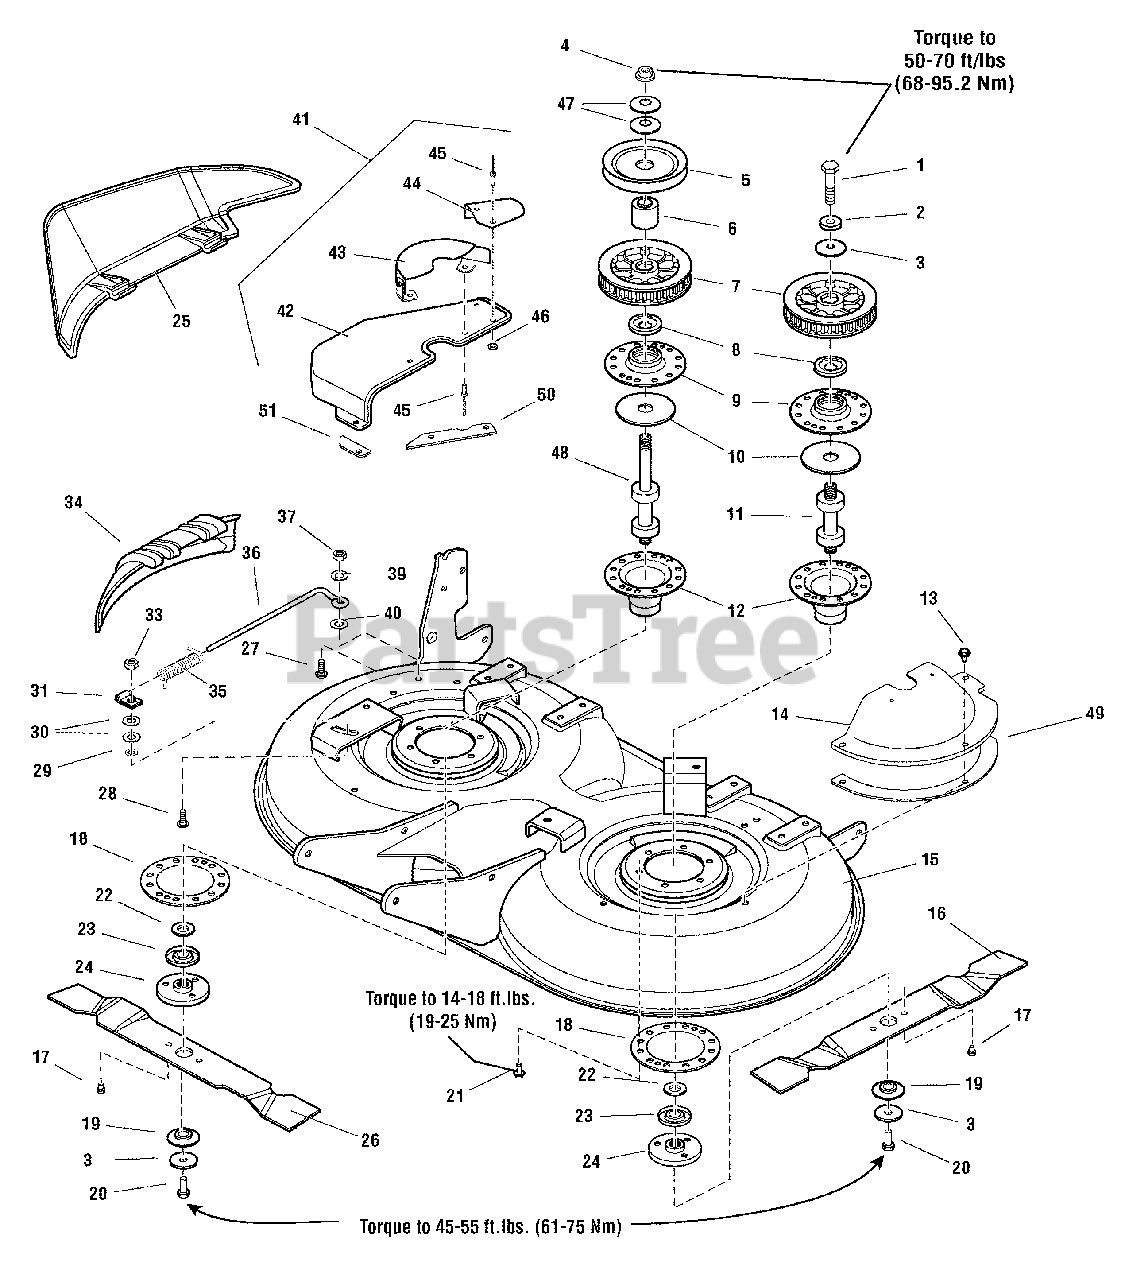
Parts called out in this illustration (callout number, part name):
1	CAPSCREW, Hex Head, 7/16-14 x 2-3/4 G8
2	WASHER, 7/16
3	WASHER, Spring
4	NUT, Hex Flange, 9/16-18
5	PULLEY, Drive 5"
5	PULLEY, Drive 6"
6	HUB
7	SPROCKET & FLANGE ASSEMBLY, w/Screws, 38 Tooth
8	SHIELD, Bearing Upper, Arbor
9	HOUSING, Arbor Top
10	GASKET, Foam Poly
11	ARBOR SHAFT & BEARINGS ASSEMBLY
12	HOUSING, Arbor Bottom with Lube Fitting
13	CAPSCREW, Taptite Hex Washer Head, 5/16-18 x 3/4
14	COVER, Arbor, LH
15	HOUSING ASSEMBLY, 40", Red
16	BLADE, Mower, LH
17	PIN, Blade
18	ADAPTOR, Arbor
19	WASHER, Spline
20	CAPSCREW, Hex Head, 7/16-14 x 2-1/4 G8
21	CAPSCREW, Taptite Hex Washer Head, 5/16-18 x 1
22	WASHER, Shim
23	SHIELD, Arbor Bearing, Lower
24	ADAPTER, Blade
25	DEFLECTOR, Discharge
26	BLADE, Mower, RH
27	BOLT, Carriage, Short Neck, 5/16-18 x 1
28	CARRIAGE BOLT, 1/4-20 x 7/8
29	NUT, Push
30	WASHER, 1/4
31	CLAMP
33	NUT, Hex 1/4-20, ESNA
34	DOOR, Mulching, Black Plastic
35	SPRING, Torsion
36	ROD, Pivot
37	NUT, Hex Lock ESNA Light, 5/16-18
39	WASHER, 5/16
40	NUT, Push
41	COVER ASSEMBLY, Arbor, RH
42	COVER, Arbor RH
43	GUARD ASSEMBLY, RH
44	GUARD, Extension
45	RIVIT, Pop
46	WASHER, 3/16 x 3/4 x 1/16
47	WASHER, Bellville, 9/16
48	ARBOR SHAFT & BEARING ASSEMBLY
49	SHIM-Cover LH 7GA 40" Mower
50	SHIM-Cover RH 7GA 6.5 LG 40" Mower
51	SHIM-Cover RH 7GA 2.8 LG 40" Mower
